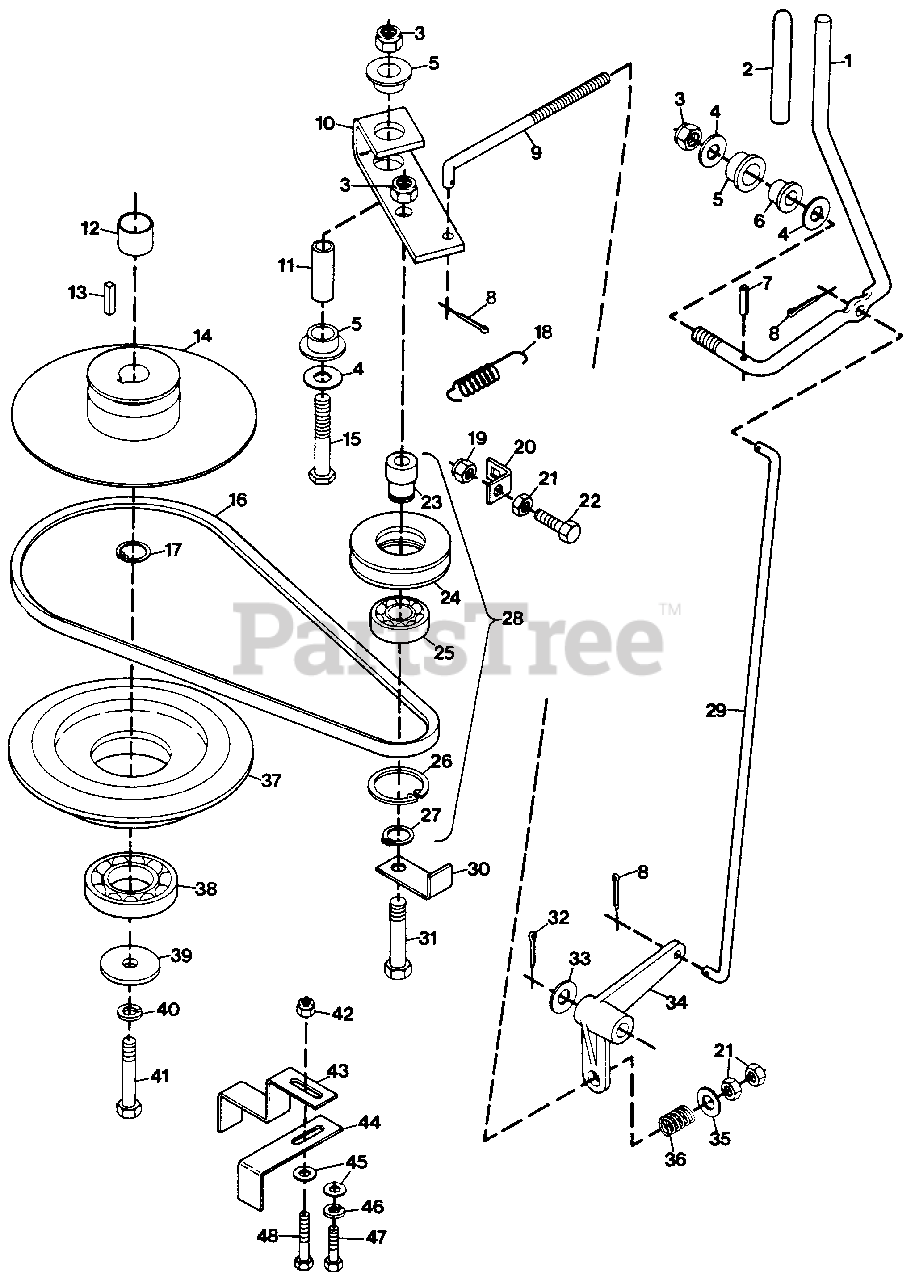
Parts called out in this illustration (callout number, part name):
1	TERMINAL, FEMALE
2	CHAIN, KEY
3	KEY, IGNITION SWITCH
4	BOOT FOR 9/16 SWITCH
5	NUT, 5/8-32 FOR SWITCH
6	WASHER, LOCK 5/8 I.T.
7	SWITCH
8	TERMINAL
9	LEVER
10	SWITCH
11	SCREW, MACHINE 10-24X.75 PHD
12	NUT, LOCK 10-24
13	HANDLE, R.H.
14	HANDLE, L.H.
15	SCREW, MACH. 10-24X1.50 PHDCR
16	HARNESS, WIRING
17	TIE, CABLE
18	BOLT, HEX 1/4-20X.625
19	MODULE, INTERLOCK RECOIL
20	NUT, LOCK 1/4-20
22	WIRE, ENGINE KILL
23	NUT, WIRE
24	SWITCH, NEUTRAL START
25	CONNECTOR, 2-WIRE SWITCH
26	WASHER, FLAT .188X.438X.049
27	BRACKET, INTERLOCK SWITCH
28	NUT, STAMPED 9/16-18
29	WIRE, GROUND
